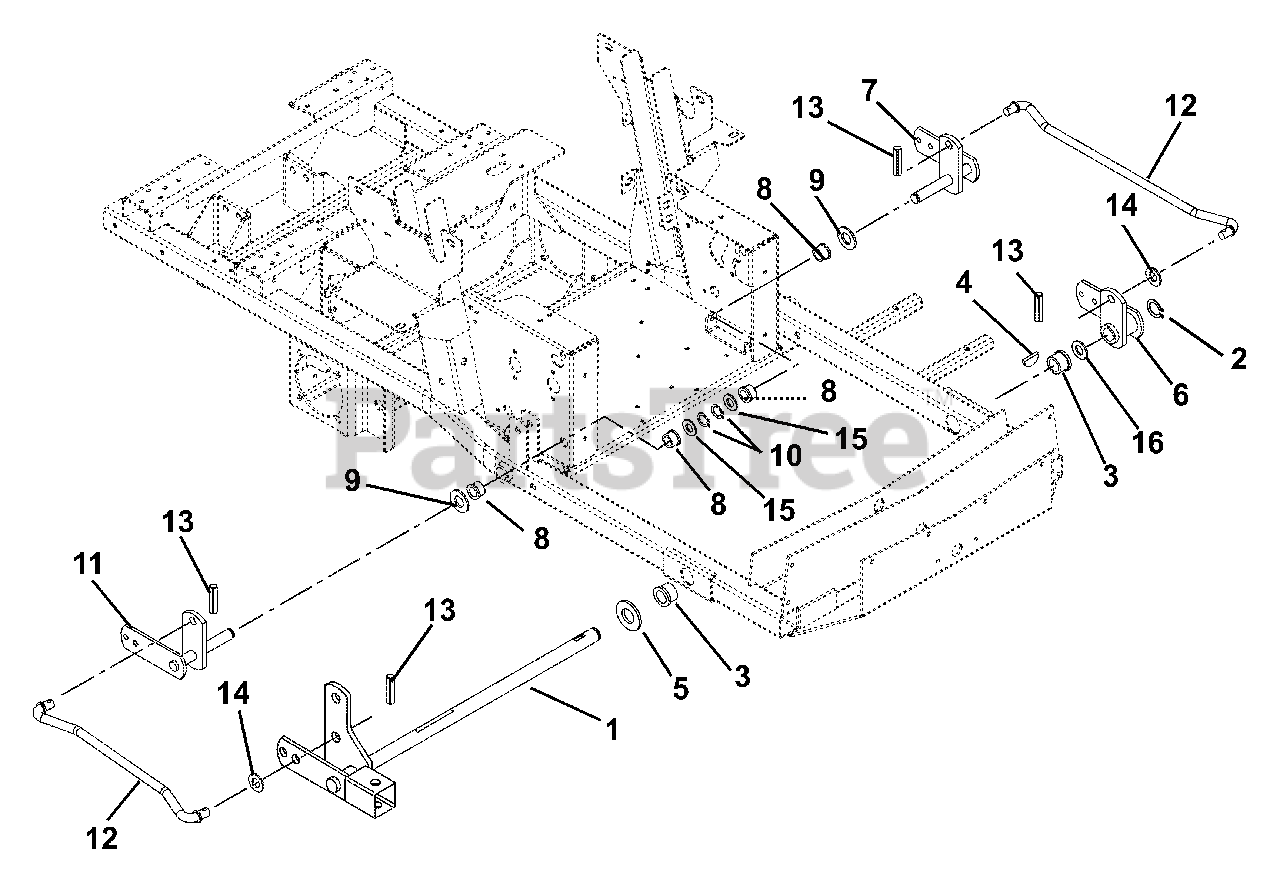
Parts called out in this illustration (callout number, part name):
1	Lift, Mower
2	Ring, Retaining External 1.00 x .078
3	Bushing, Flange Nylon 1.02 x 1.385 x .75 x 1.75
4	Key, Woodruff .25 x 1.00
5	Washer, Flat Steel 1.063 x 2.00 x .134
6	Weldment, Lift Arm-Front
7	Weldment, Rear Lift Arm-Left Hand
8	Bushing, Flange Nylon .762 x 1.0 x .58 x 1.48
9	Washer, Hardened Steel .758 x 1.23 x .031
10	Ring-Retaining-External .689 x .077
11	Weldment, Rear Lift Arm- Right Hand
12	Rod, Lift Assist 19.35"
13	Pin, Roll .25 x 1.25 Stainless Steel
14	Washer, Flat Steel .630 x 1.25 x .062
15	Washer, Flat Steel .755 x 1.25 x .125
16	Washer, Hardened Thrust 1.00 x 1.55 x .03
